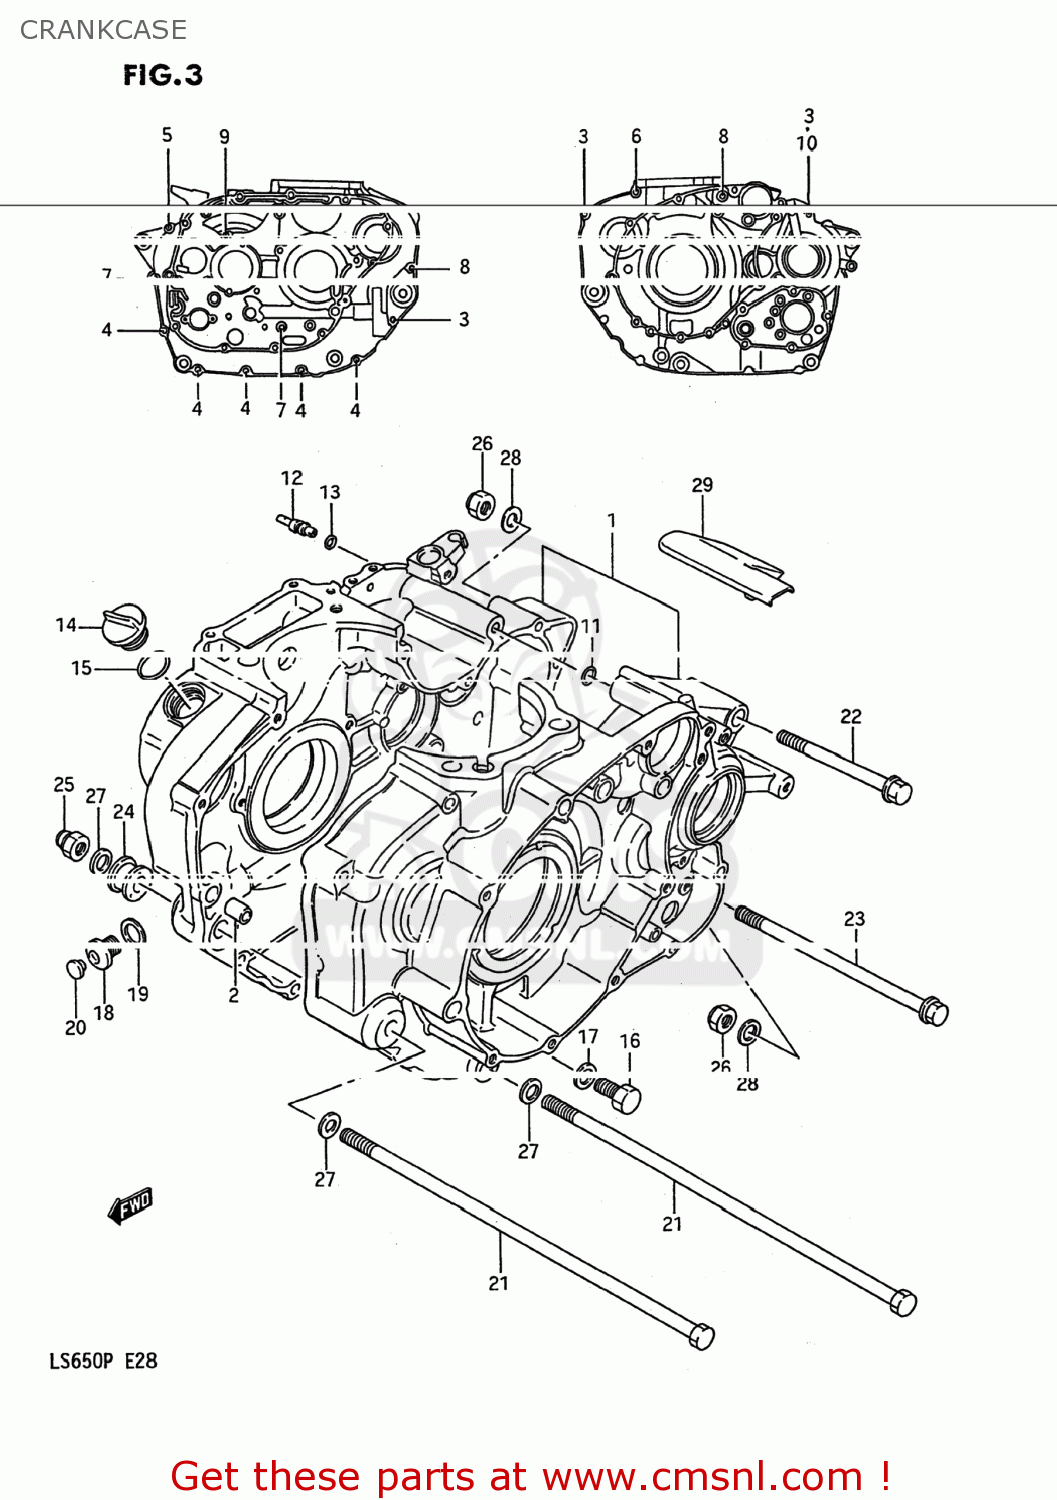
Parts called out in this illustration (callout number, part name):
1	CRANKCASE SET
2	PIN (11X20)(SUS)
3	BOLT
4	BOLT
5	BOLT
6	BOLT
7	BOLT
8	BOLT
9	BOLT
10	GASKET(5.8X13X1.2) (NAS)
11	O RING(D:2.4,ID:9.6)
12	JET,OIL GALLERY(18)
13	O RING(D:1.2,ID:4)
14	PLUG(20X10)
15	O RING(D:3.1,ID:16.8)
16	BOLT
17	GASKET(12.1X16.2X3.7) (NAS)
18	PLUG,14X12
19	GASKET(14X19.2X2) (NAS)
20	CAP(OD:12)
21	BOLT(10X323)
22	BOLT(10X105)
23	BOLT(10X180)
24	SPACER,ENGINE MOUNT(L20)
25	NUT
26	NUT
27	WASHER
28	WASHER 10MM
29	COVER,CRANKCASE START
